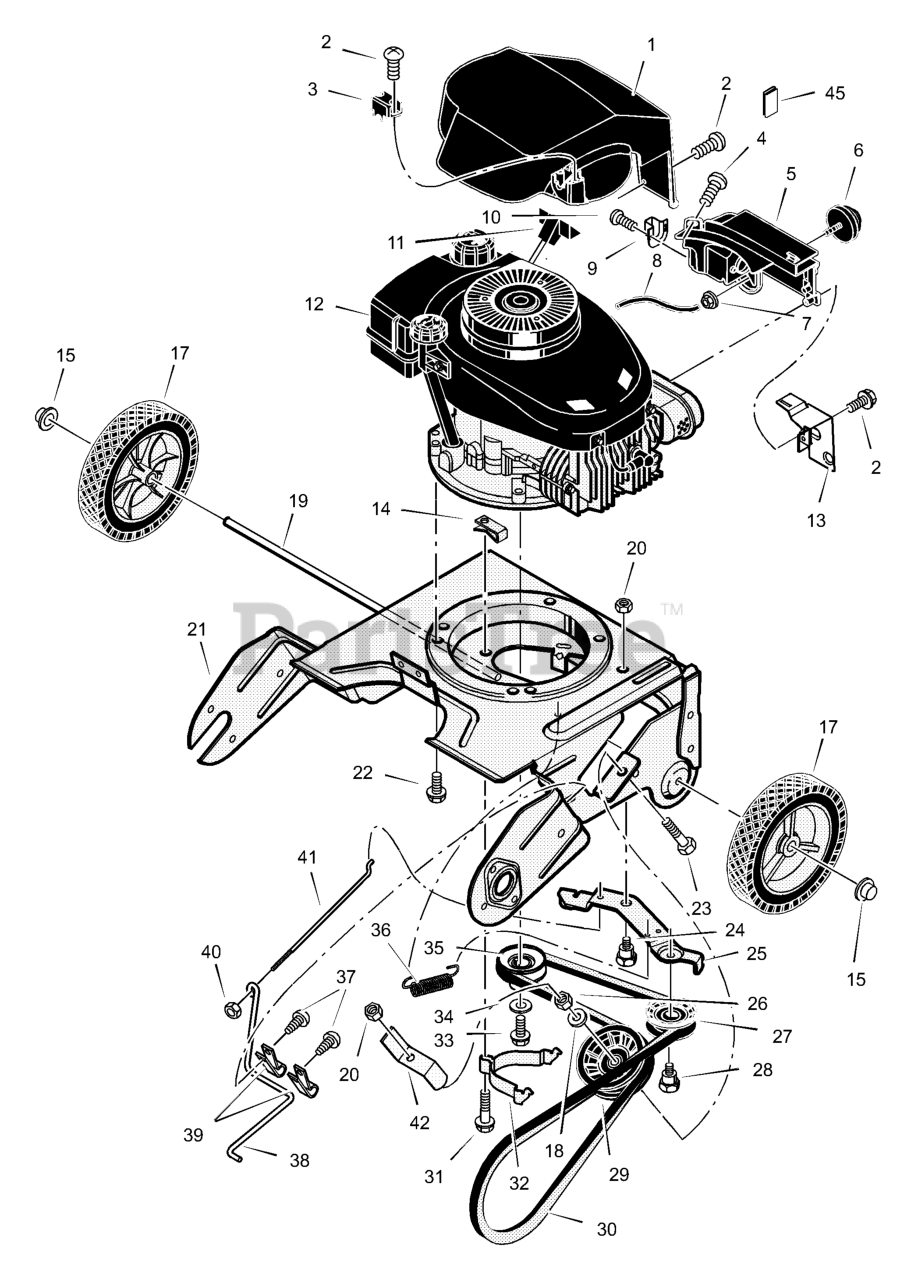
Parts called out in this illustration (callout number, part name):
1	Cover, Top
3	Bracket, Crank Rod
5	Box, Heater
6	Primerbulb, Red
9	Deflector, Carburetor
11	Handle, Starter
12	Engine
13	Shield Assembly, Heat
14	Retainer
15	Nut, Push Cap
17	Wheel & Tire
18	Washer
21	Frame, Motor Box
24	Bolt, Shoulder
25	Bracket, Idler Arm
27	Pulley, Idler -V-Belt
28	Bolt, Shoulder
29	Pulley, Flat Idler
32	Guide, Belt
33	Screw
34	Washer
35	Pulley 2.50 X 4L .750 I.D.
38	Arm, Brake
40	Nut
41	Rod, Adjustment
42	Guide, Belt
45	Clip, Tinnerman
